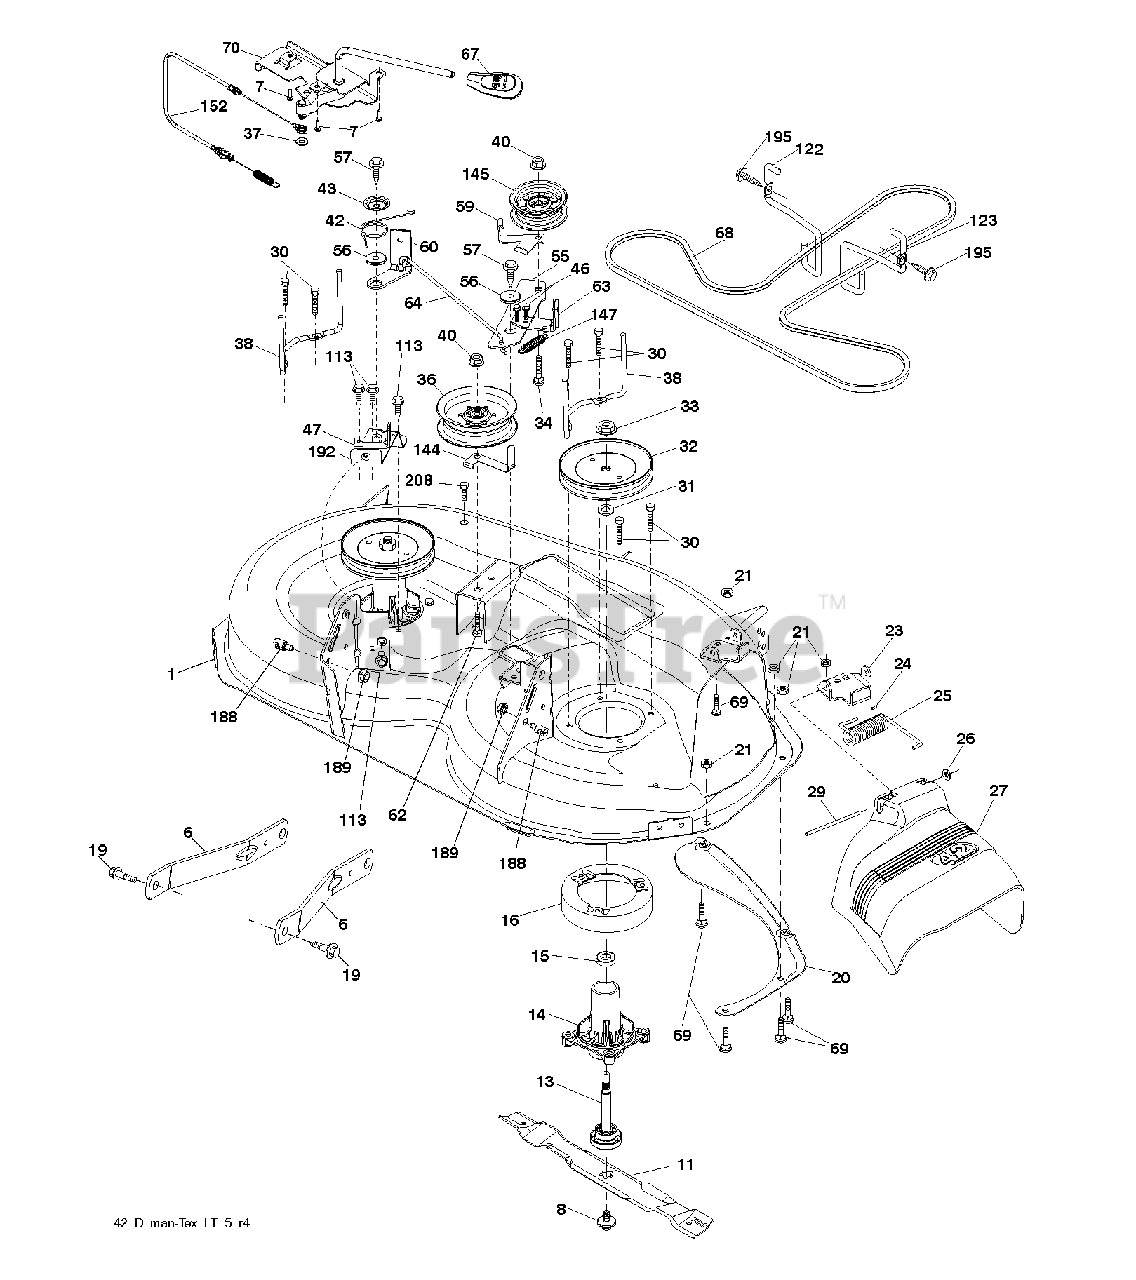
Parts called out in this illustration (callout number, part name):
1	DECK.WELDMENT.42"
6	ARM.SUSPENSION.MOWER.R
7	SCREW.#10 X 0.750.BOS THREAD
8	BOLT.WASHER.ASM.7/16-2
11	42" HI-LIFT BLADE
13	SHAFT.ASM.MDRL.N/GREASE.38
14	HOUSING MANDREL
16	STRIPPER, MWR ROUND
19	BOLT.SHOULDER
20	BAFFLE.VORTEX
21	LOCKNUT
23	BRKT.DEFLECTOR.38"2005+
24	CAP-SLEEVE LT
25	SPRING.TORSION.DEFLECT
26	NUT PUSH M
27	SHIELD.DEFLECTOR.MOWER.42"BLAC
29	ROD.HINGE
30	SCREW, WASHER HEAD
31	WASHER.SPACER.MANDREL
32	PULLEY.MANDREL.5.438.PD
33	NUT.FLANGE.LOCK.TOP
34	BOLT.3/8-16X1.50
36	PULLEY.IDLER.2006
38	KEEPER.BELT.LH.MANDREL
40	NUT LOCK FLG 3/8-16 UNC
42	SPRING.TORSION.BRAKE
43	SRPING.TORSION.RETAINE
46	SCREW.1/4-20X5/8
47	BRKT.CLUTCH.CABLE
55	IDLER.ARM
56	SPACER.RETAINER
57	SCREW 3/8-16X1
59	GUARD, BELT
60	ARM BRAKE MOWER
62	BOLT
63	ARM BRAKE MOWER
64	LINK BRAKE
67	HANDLE.CLUTCH.CABLE.LT
68	BELT.DRIVE.MOWER.TEX.42"
69	BOLT
70	CLUTCH.ASM.MANUAL.LT.PRED
113	BOLT.5/16HEX.WHS.HD
117	WHEEL.GAGE.HALF.SPOKED
118	LOCKNUT
119	WASHER
122	KEEPER BELT ENGINE LH
123	KEEPER BELT RH
144	KEEPER.BELT.MOWER
145	PULLEY.IDLER.48"PRIMARY
147	RETURN SPRING
152	CLUTCH CABLE
188	STUD.FASTNER.W/ANTI-ROTATE
189	NUT LOCK HEX FLANGE 5/16-18
192	BRKT.BRAKE.STAND.LH.
195	SCREW, 3/8-16X3/4
208	SCREW 3/8-16X1/2
